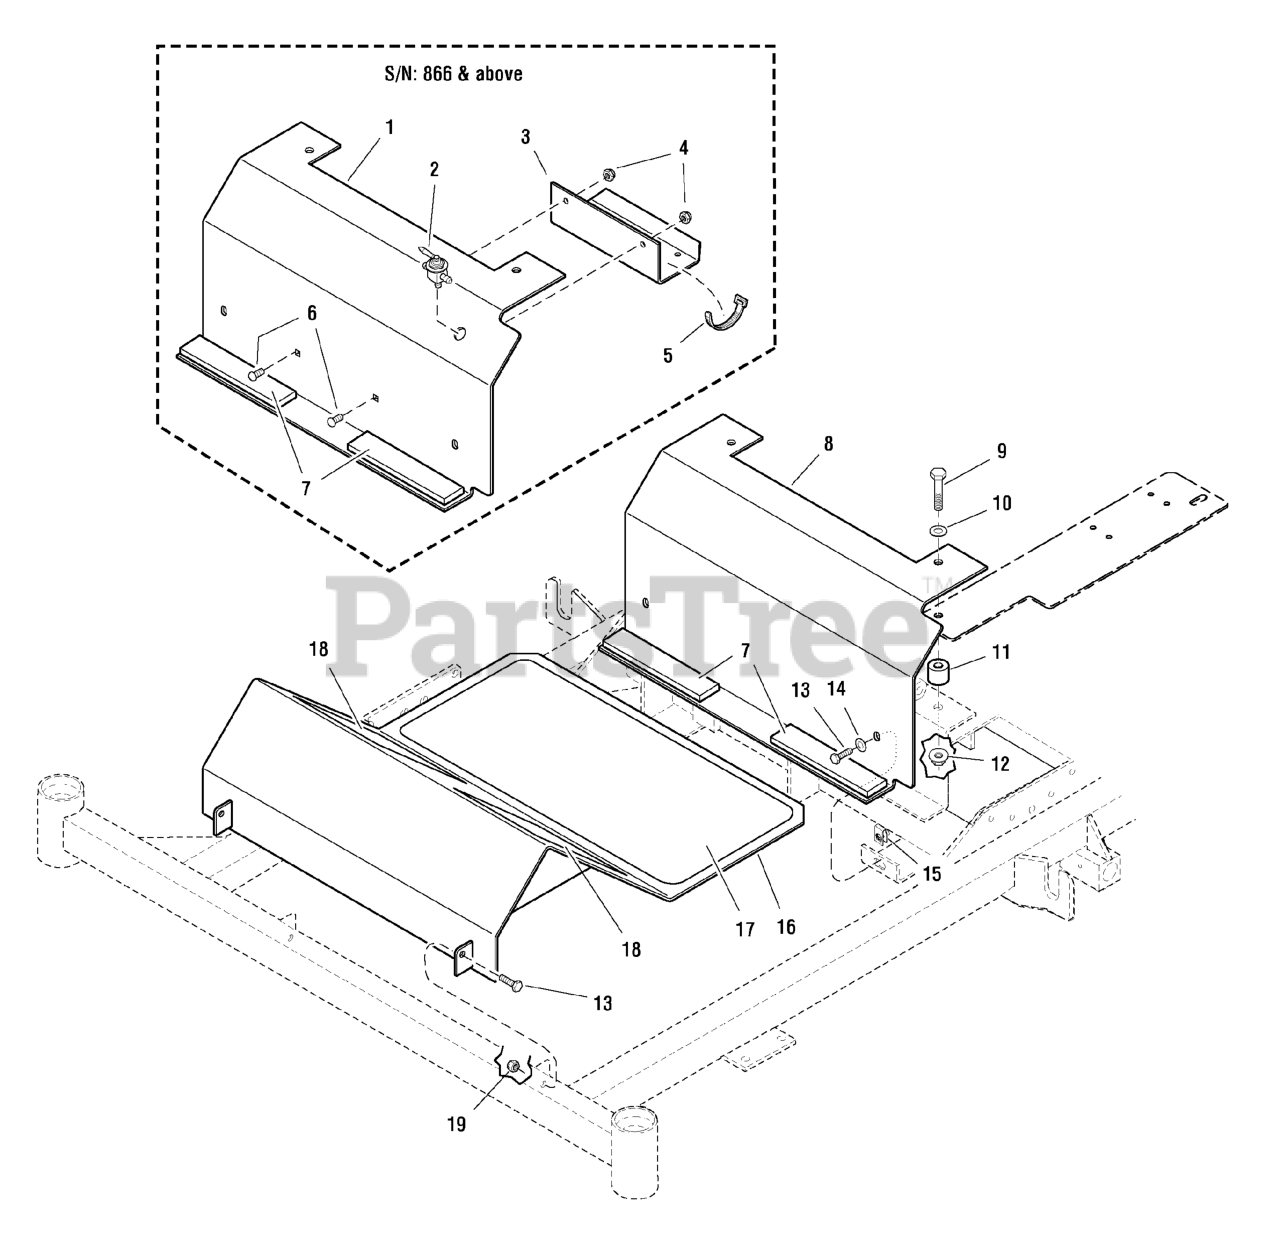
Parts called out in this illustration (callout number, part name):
1	BRAKE COVER PANEL ASSEMBLY
2	VALVE, Fuel Shut Off
3	FUEL LINE GUIDE
4	NUT, 1/4-20 HEX NYLON LOCK
5	SPACER, .33 X .63 X .50, CZ
6	BOLT, 1/4-20 X 3/4", CARRIAGE
7	Pad, Rubber Mount
8	BRAKE COVER PANEL
9	BOLT, 3/8-16 X 2, GD5, CZ
10	WASHER, 3/8 SAE
11	SPACER, .39 X 1.00 X .88, CZ
12	NUT, 3/8-16 Hex Large Serrated Flange
13	BOLT, 5/16-18 X 1" GRD5 YZ
13	BAR, PUMP LINK, OFFSET - RED
14	WASHER, 5/16" SAE
15	BODY CLIP, 5/16-18-7GA MATERIAL
16	FLOOR PLATE
17	SAFETY WALK, 11.50 X 19.00
18	SAFETY WALK
19	NUT, Hex, Nylon Locking, 5/16-18
